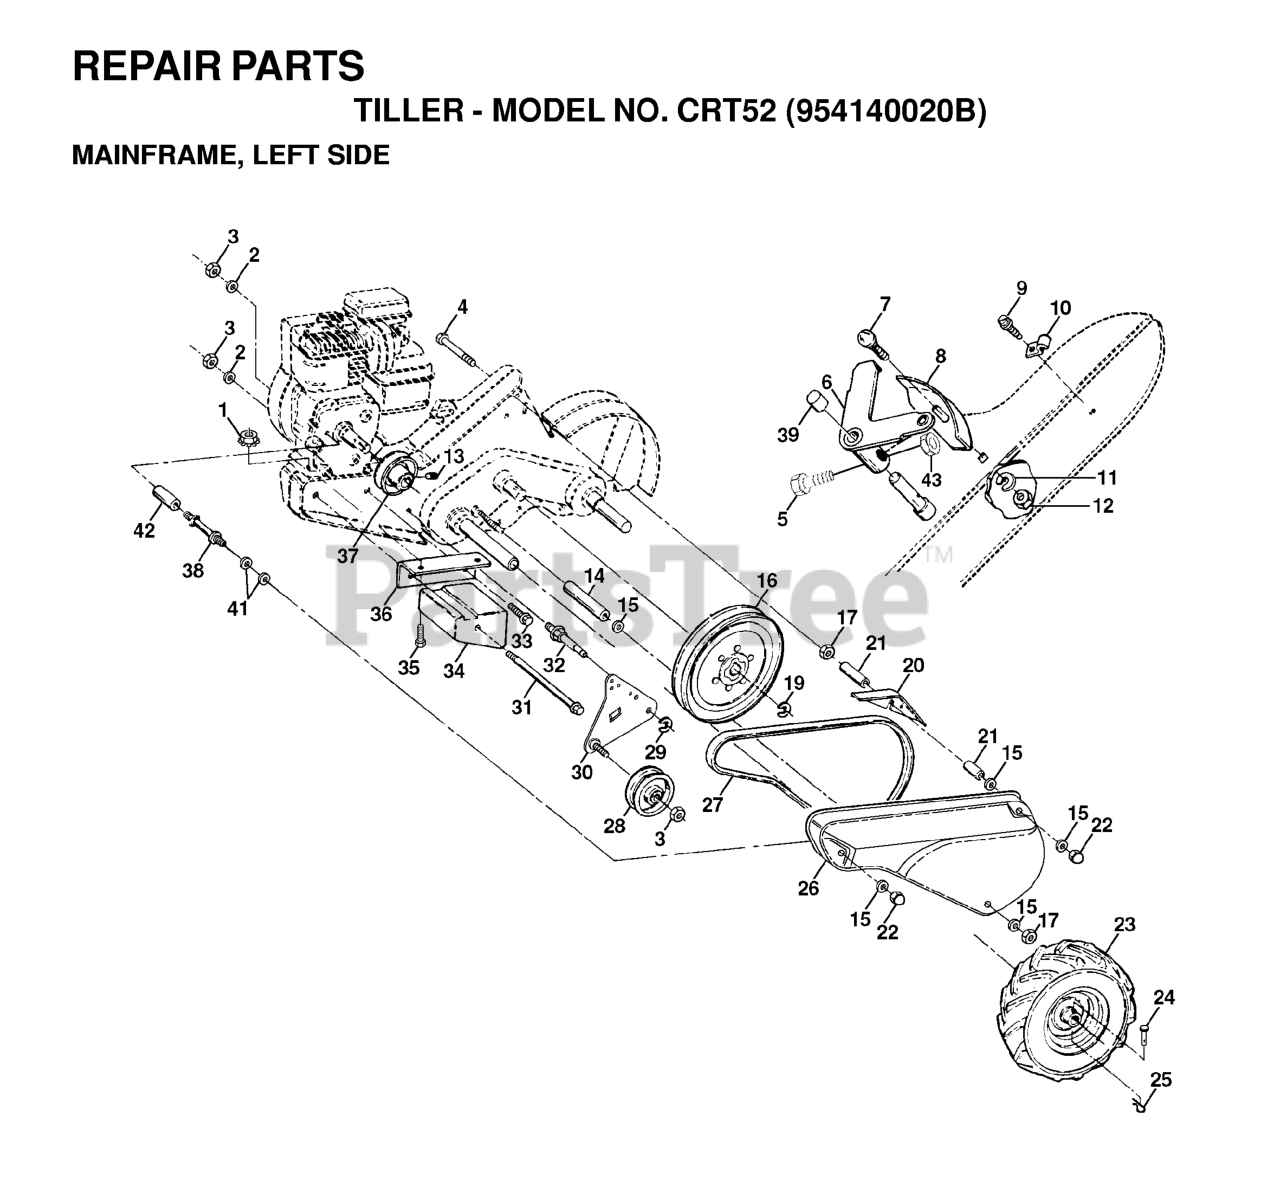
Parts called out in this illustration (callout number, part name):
1	WHEEL.STEER.HUSQ.SR.498.OVMLD
2	AXLE.CAST.IRON
4	SPINDLE.WELDED.LH.16"TEX
5	SPINDLE.WELDED.RH.16"TEX
6	WASHER THRUST
9	CAP.SPINDLE.BLACK
14	SLW 3/8 STD
15	NUT CROWNLOCK 3/8-24
16	SHAFT.STEER.2HIGH.SPLND.PLATED
19	PLATE.STEER.DDL.NLT/NG
21	ADAPTER.WHEEL.STEER.SPLND.ALUM
22	BEARING.SUBASM.SHAFT.STEER.LOW
26	INSERT.CAP.WHL.STRG.HUSQ.PREM
28	SCREW, 3/8-16X3/4
35	GEAR.SECTOR.PLATE.DDL.
45	WASHER.3/8ID.2-3/8OD.12GA.PLTD
50	NUT LOCK FLG 3/8-16 UNC
53	WASHER.HARDENED
55	SPACER.BRACE.AXLE
58	BOLT.SHOULDER.SECTOR.P
59	WASHER.THURST.SECTOR.S
60	NUT FLANGE LOCK 5/8-11
61	LINK.ASM.DRAG.ADJUST.LH.PLATED
62	LINK.ASM.DRAG.ADJUST.RH.PLATED
63	SCREW
64	RETAINER.CLIP.SPRING.S
65	BRACE.AXLE.FRONT.NLT/N
66	BOLT HEX FGHD 7/16-14 X 3 SERR
67	BUSHING.PM.FRONT AXLE
68	NUT.LOCK.FLANGE.7/16
69	WASHER.1.5X.505X.118
70	BRACKET.FRT.DECK.SUSP.RR.MT431
75	PINION.ZINC PLATED
76	SCREW HEAD SOCKET LRVB
78	THRUST WASHER
122	CAP.GEAR.SECTOR.TEX
